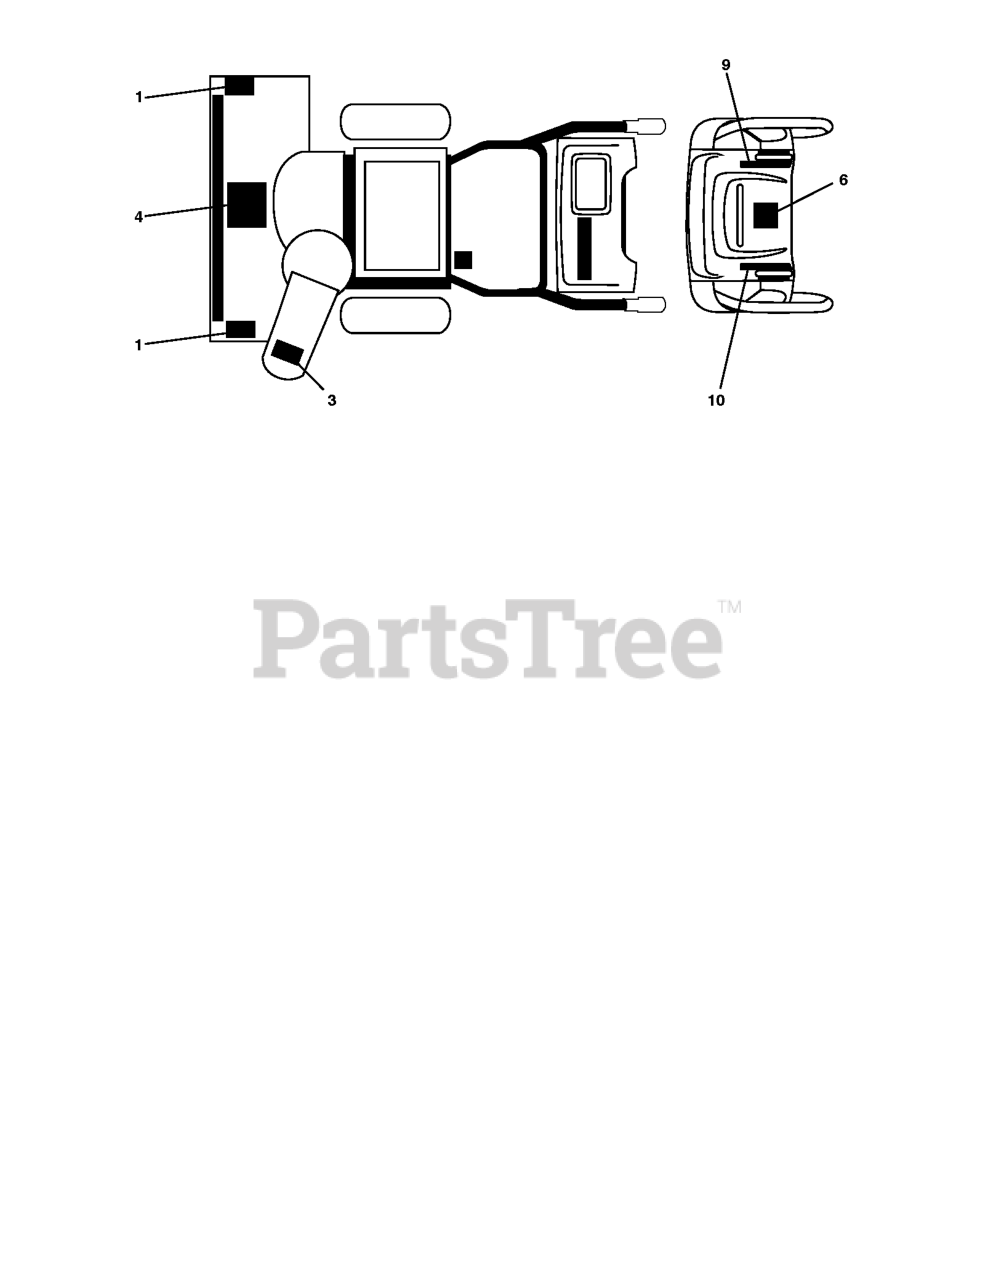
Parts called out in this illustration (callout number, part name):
1	DECAL.SNOWTHR.AUGER
3	DECAL.SNOWTHR.CHUTE.SAFETY
4	DECAL.SNOWTR.READ.OWN.MAN.E/F
6	DECAL.CONSOLE.SNOW.INST.ENG/FR
9	DECAL.CONS.RT.SPD/LEV/PWRST.
10	DECAL.CONS.LT.SPD/LEV/PWRST.
